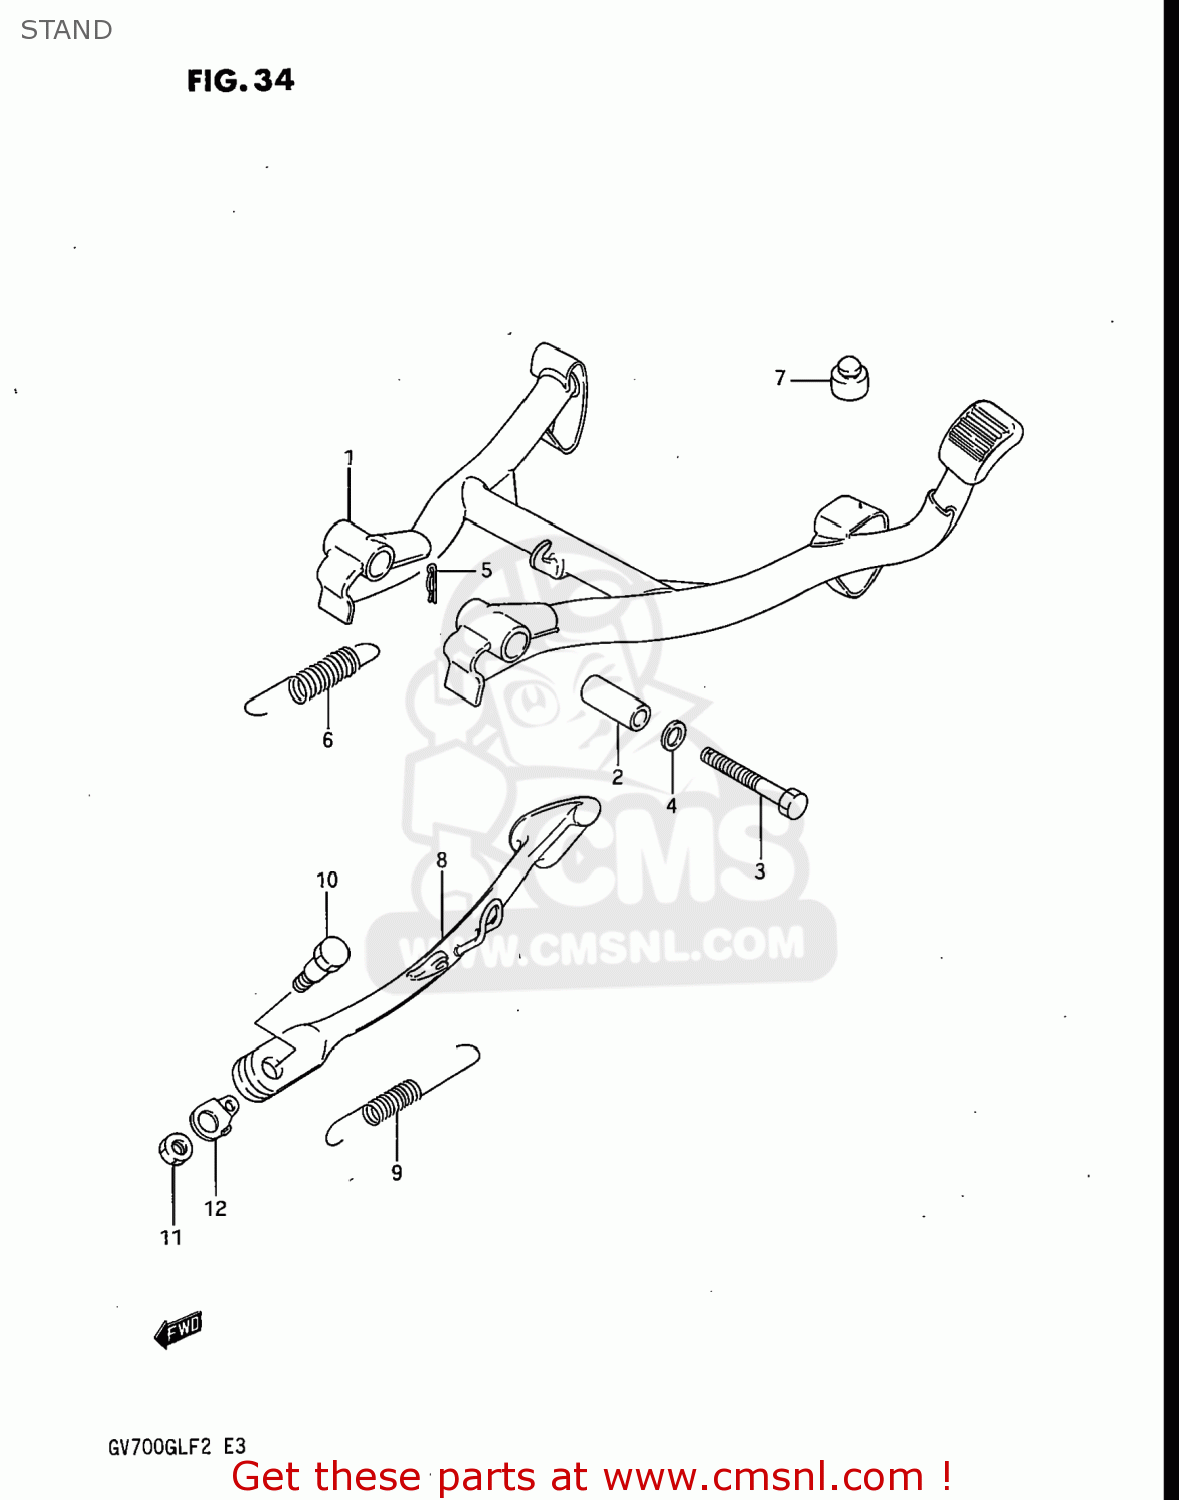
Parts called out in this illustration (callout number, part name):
1	STAND,CENTER
2	SPACER(10X16X38.8)
3	BOLT
4	LOCK WASHER
5	CLIP
6	SPRING
7	CUSHION
8	STAND,SIDE
9	SPRING
10	BOLT(10X34)
11	NUT
12	PLATE,SIDE STAND WARNING
